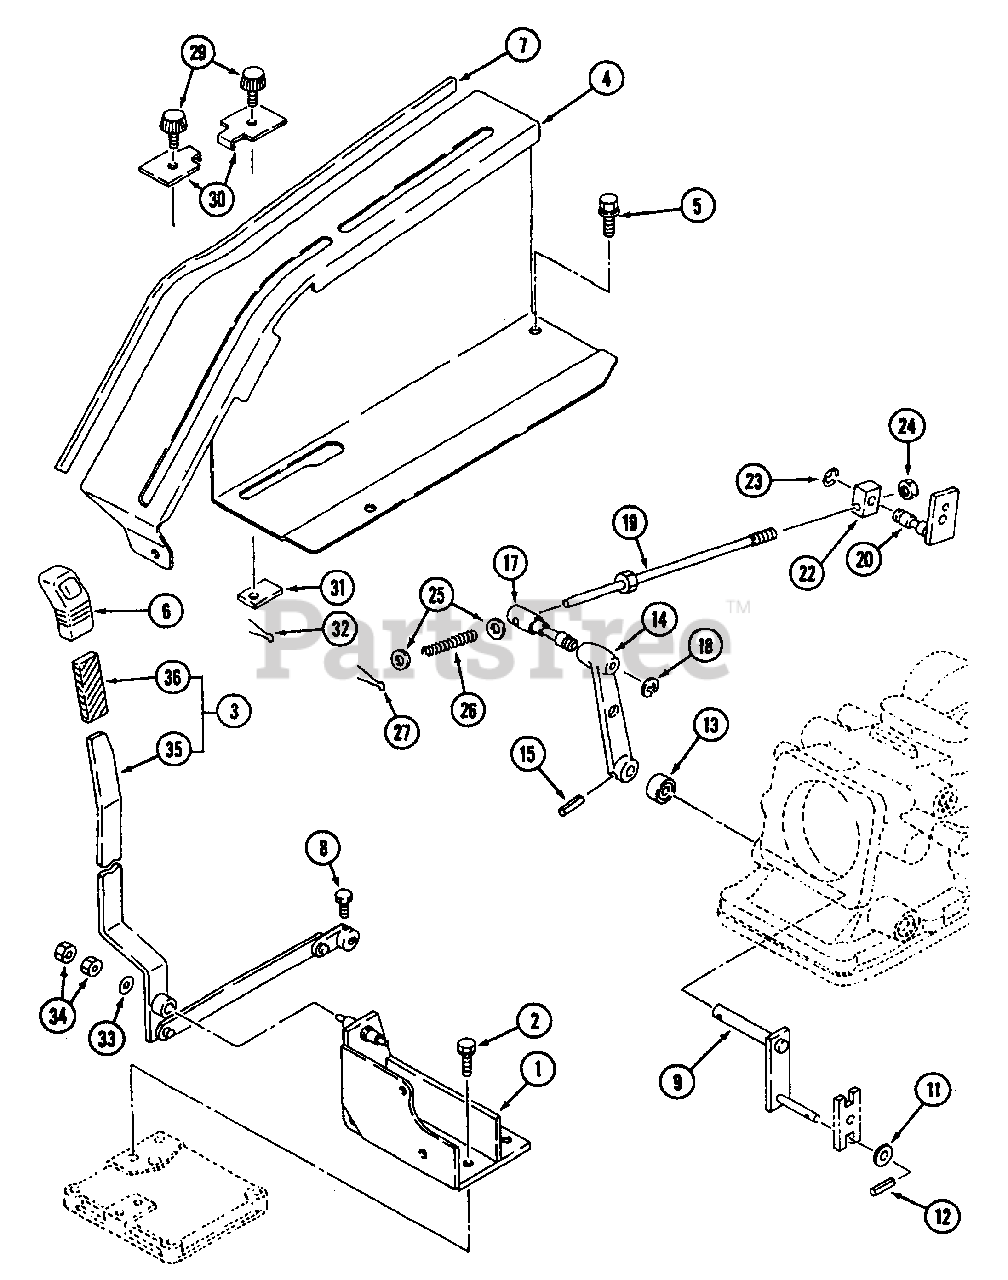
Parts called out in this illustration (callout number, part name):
3	Lever, P/C Ass'y.
4	Lever Guide R.H.
14	Arm, Feedback
22	Joint
27	Pin, Split
35	Lever, P/C Ass'y.
